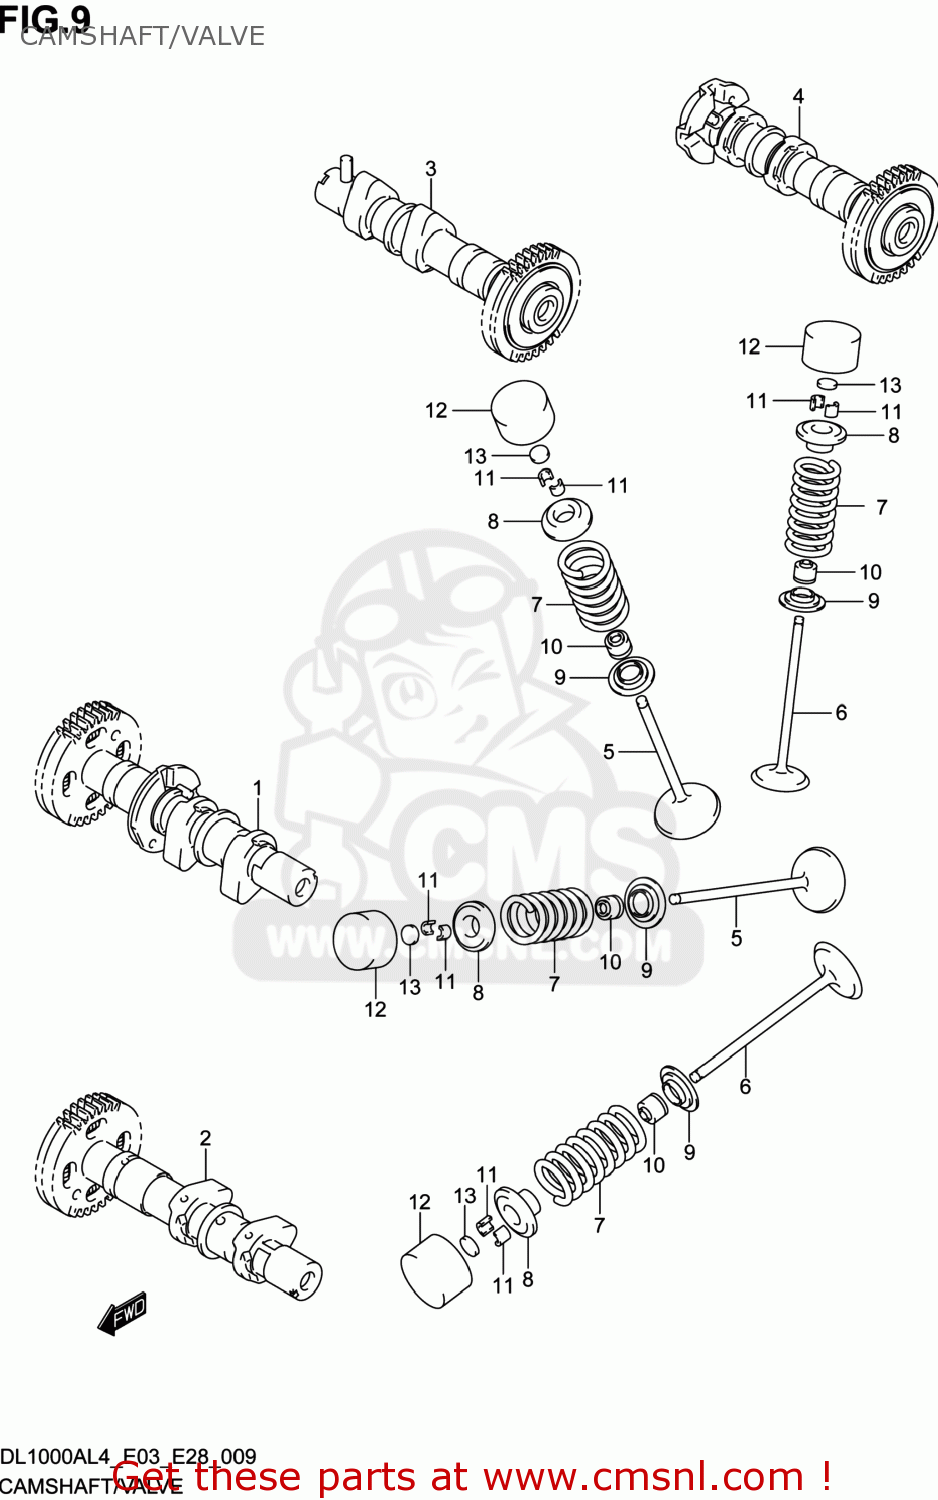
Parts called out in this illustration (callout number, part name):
1	CAMSHAFT ASSY,INTAKE FR
2	CAMSHAFT ASSY,EXHAUST FR
3	CAMSHAFT ASSY,INTAKE RR
4	CAMSHAFT ASSY,EXHAUST RR
5	VALVE,INTAKE
6	VALVE,EXHAUST
7	SPRING,VALVE
8	RETAINER,VALVE SPRING
9	SEAT,VALVE SPRING
10	SEAL,OIL(5.5X11X8.2)
11	COTTER,VALVE
12	TAPPET
13	SHIM,TAPPET(T:2.3)
14	SHIM SET,TAPPET
15	CASE,TAPPET SHIM
